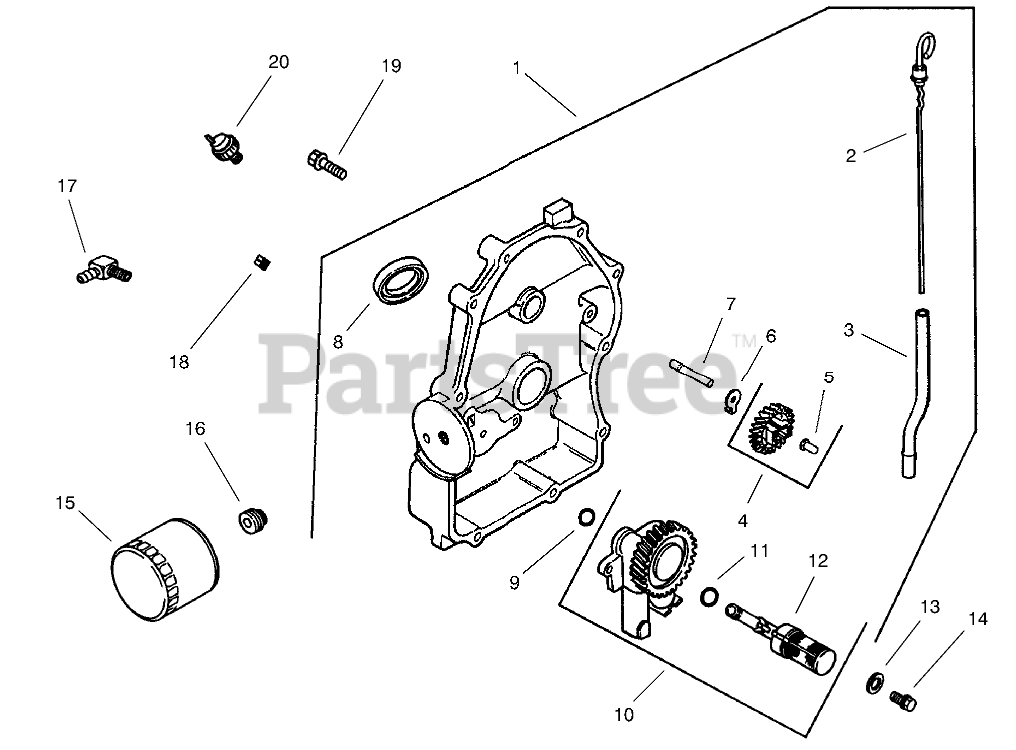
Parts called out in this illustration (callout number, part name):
1	Plate, closure assembly (Includes 2-12)
2	Dipstick
3	Tube-Dipstick
4	Kit, governor gear (Includes 5)
5	Pin-Governor
6	Tab-Locking
7	Shaft-Gear, Governor
8	Seal-Oil
9	O Ring
10	Oil pump assembly (Includes 11,12)
11	O-Ring
12	Pick Up-Oil
13	Washer
14	Screw
15	Filter-Oil
16	Nipple-Filter, Oil
17	Connector
18	Plug
19	Screw
20	Switch, pressure
